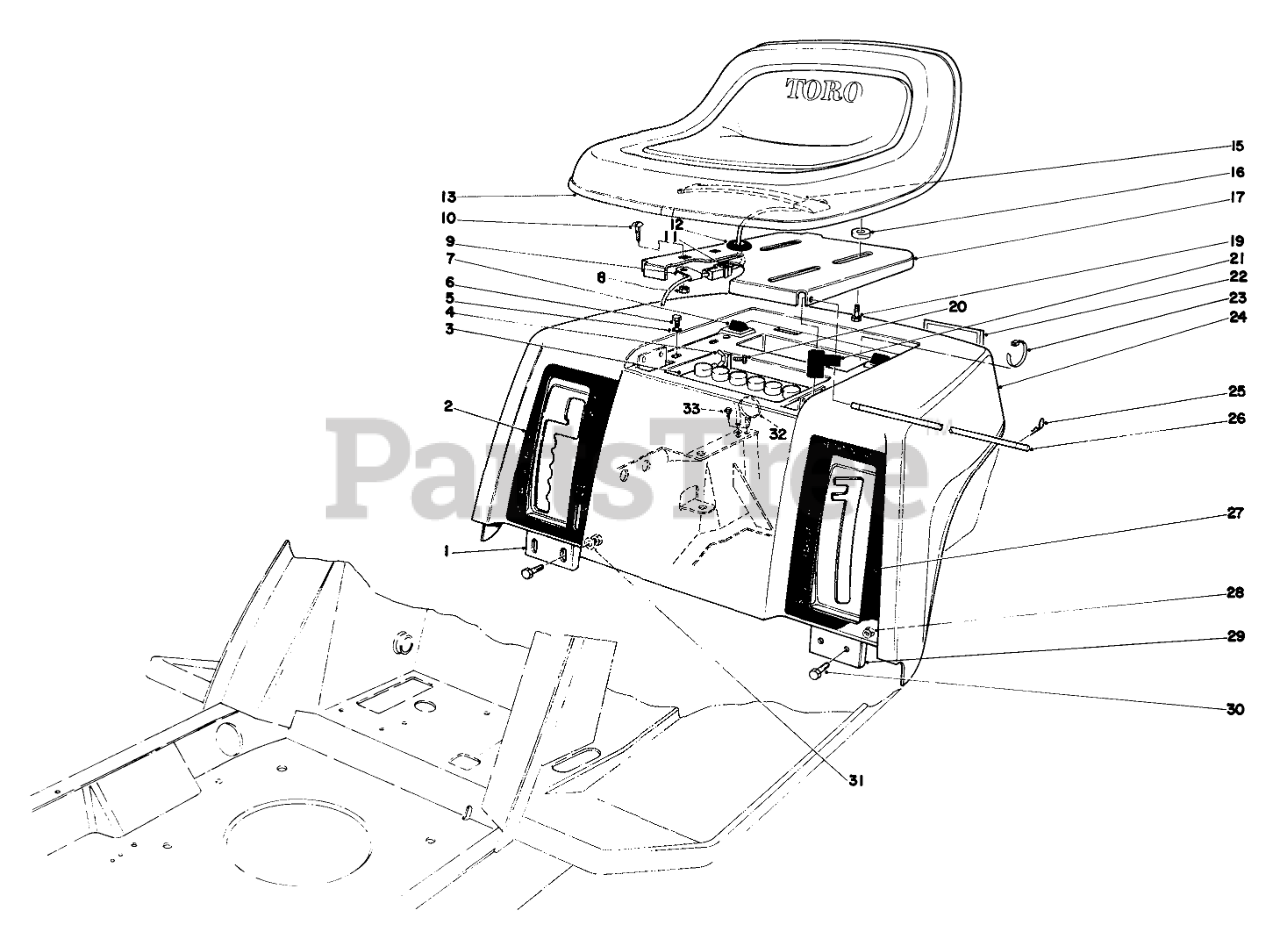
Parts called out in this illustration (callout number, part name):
1	DETENT PLATE B
2	Decal Transmission
3	Battery
4	NUT-WING
5	WASHER
6	SCREW-HWHTF
7	SEAT BUMPER
8	NUT-KEPS
9	CLAMP
10	SCREW-CARR
11	Female Connector
12	GROMMET
15	SWITCH-SEAT
16	SPACER-PIN, MOUNTING
17	SEAT SUPPORT R
19	SCREW-HHF
20	SCREW-HH
21	BOOT-TERMINAL
22	REFLECTOR
24	Rear Body (Incl. Ref. #2 & 27)
25	PIN-COTTER
26	PIVOT-SEAT
27	Decal Height of Cut
28	NUT-LOCK, CONE
29	Quadrant Height of Cut
30	SCREW-HH
31	WASHER-PLAIN
32	TIE-MOUNT, PUSH
33	SCREW-HWHTF
